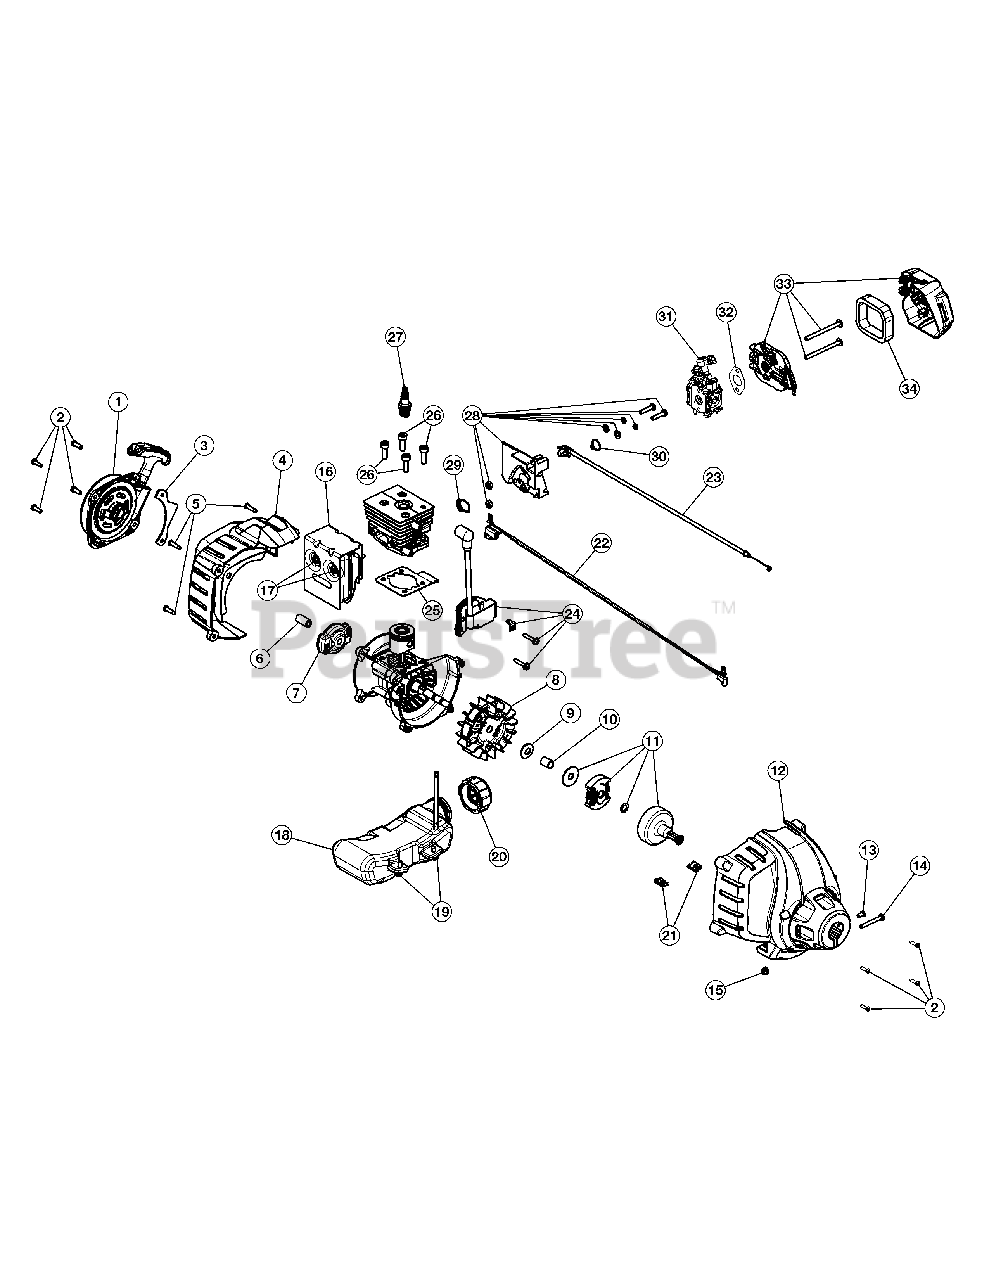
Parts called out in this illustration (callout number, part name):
1	Starter Assembly
2	Starter Screw
3	Starter Assembly Guard
4	Rear Engine Cover
5	Cover Screw
7	Pawl Assembly
8	Flywheel Assembly
11	Clutch Assembly
12	Clutch Cover Assembly
13	Anti-rotation Screw
14	Clamp Screw
15	Clamp Nut
16	Muffler Assembly
17	Muffler Screw
18	Fuel Tank Assembly
21	U-shaped Nut
22	Lead Wires
23	Throttle Cable
24	Module Assembly
25	Cylinder Gasket
26	Cylinder Bolt
27	Spark Plug
28	Insulator Assembly
29	Insulator O-Ring
30	Carburetor O-Ring
31	Carburetor
32	Carburetor Gasket
33	Air Cleaner Assembly
34	Air Cleaner Filter
